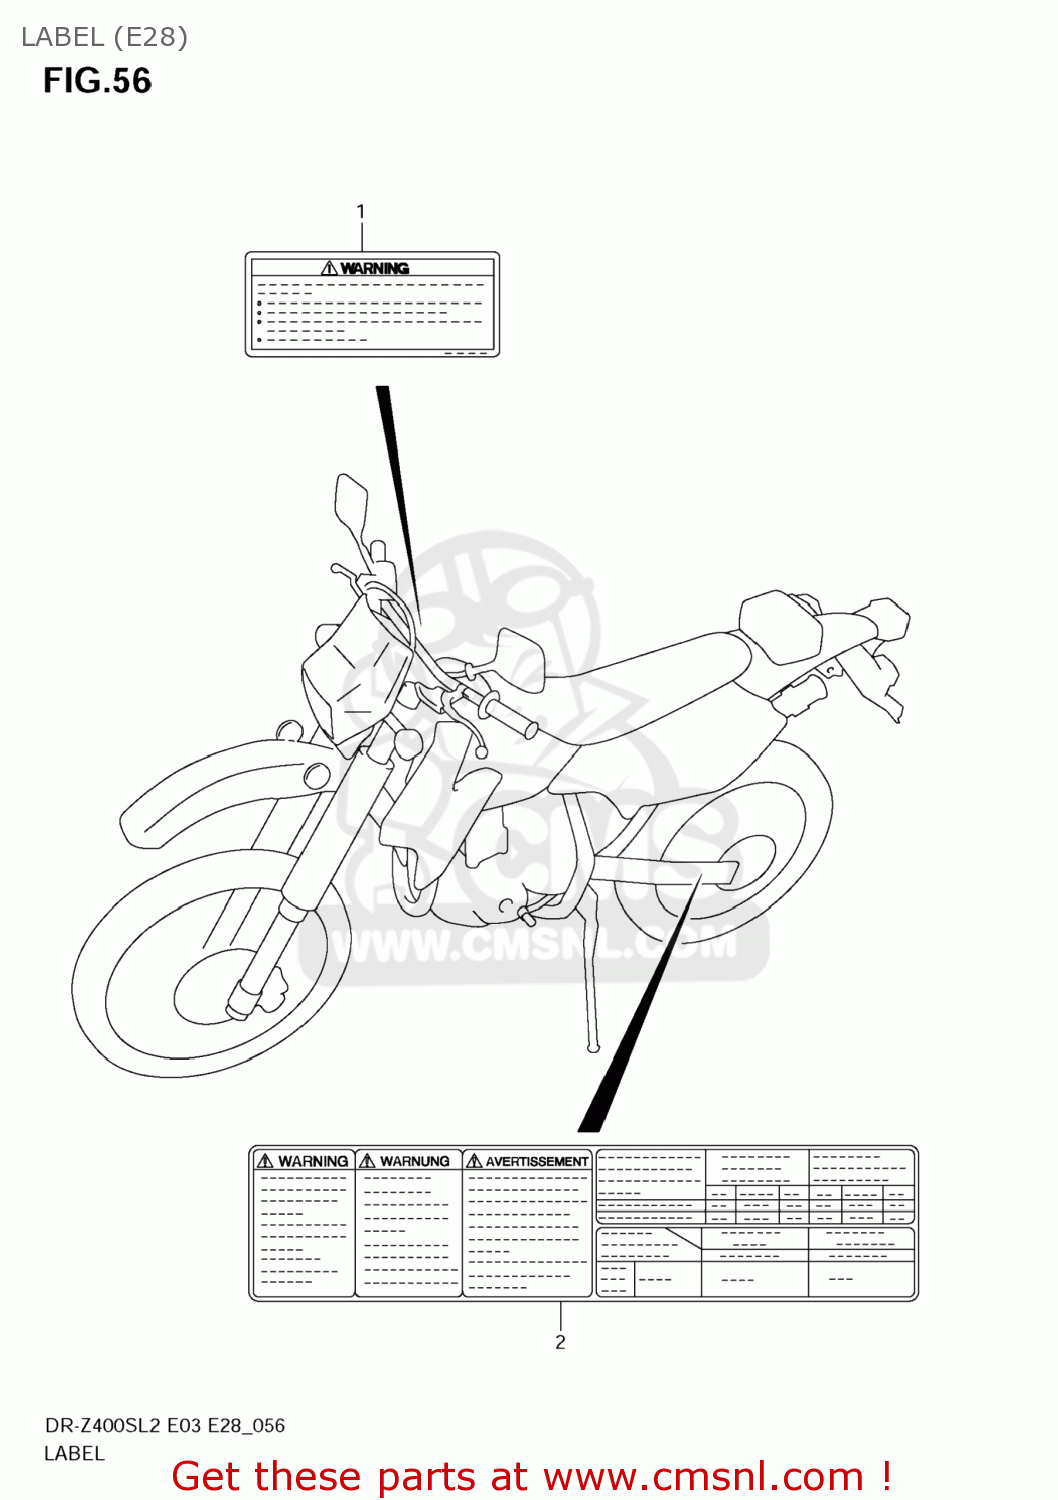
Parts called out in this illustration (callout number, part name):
1	LABEL,GENERAL WARNING
2	LABEL,TIRE INFORMATION
3	MANUAL,OWNER'S
